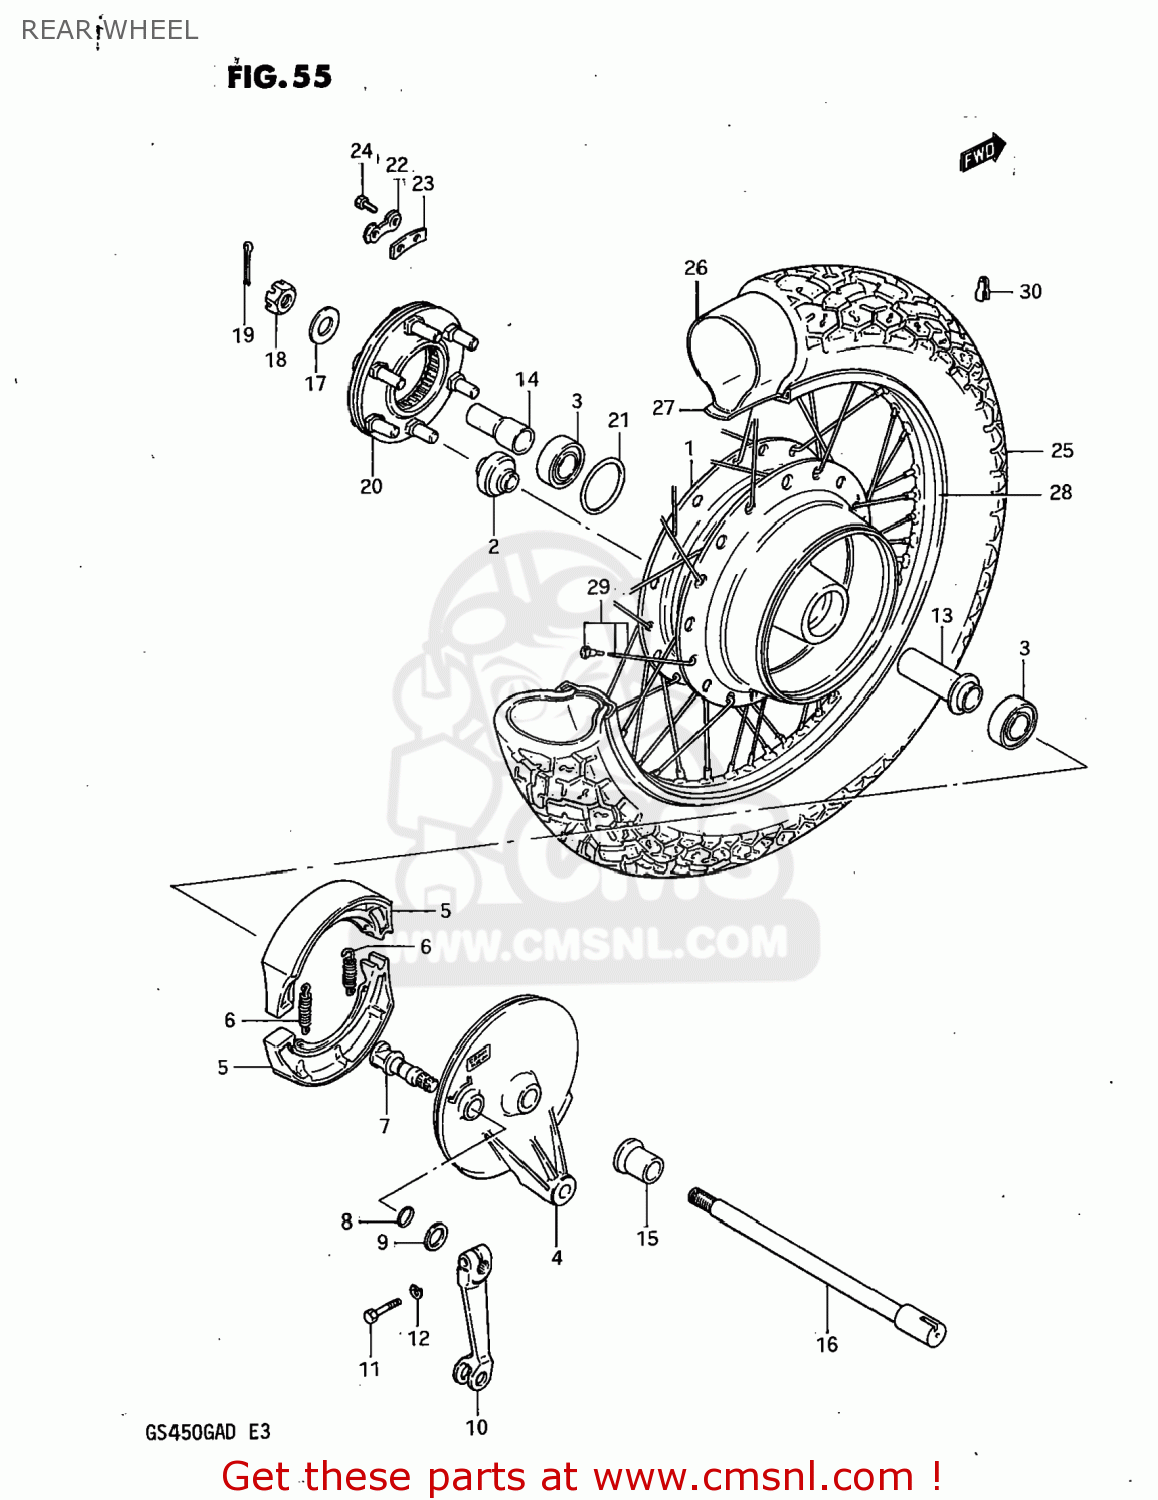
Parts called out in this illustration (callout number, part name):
1	HUB,REAR
2	CUSHION,REAR DRUM
3	BEARING
4	PANEL,REAR HUB
5	SHOE,BRAKE
6	SPRING,BRAKE SHOE
7	CAM,FRONT BRAKE
8	O-RING,BOSS
9	WASHER (15X24X1.6)
10	LEVER,RR BRAKE CAM
11	BOLT
12	LOCK WASHER
13	SPACER,REAR HUB BEARING
14	SPACER,REAR AXLE,LEFT
15	SPACER,REAR AXLE,RIGHT
16	AXLE,REAR
17	WASHER(16.5X36X3.2)
18	NUT
19	PIN,COTTER
20	JOINT ASSEMBLY,REAR HUB DRUM
21	O RING(D:2.1,ID:65)
22	WASHER
23	WASHER,THRUST(T:1.6)
24	BOLT(6X16)
25	TIRE
26	TUBE ASSY,WHEEL,INNER 4.60-16
27	PROTECTOR,INNER TUBE
28	RIM,FRONT WHEEL (2.15X16)
29	SPOKE SET,REAR WHEEL
30	BALANCER,WHEEL (B)
